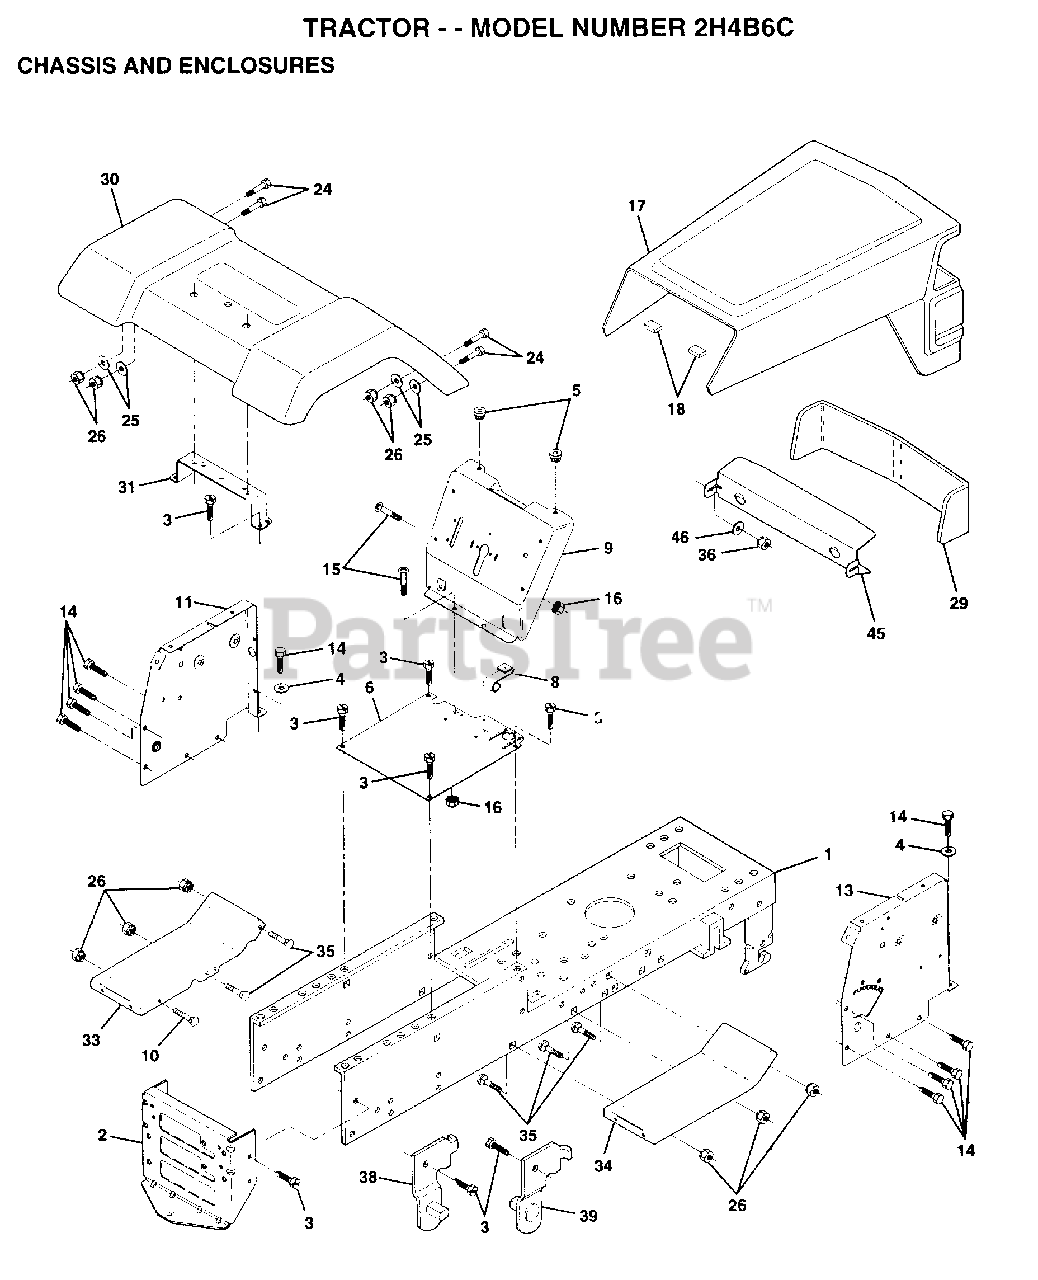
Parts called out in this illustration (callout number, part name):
1	CHASSIS.WLD.11GA
3	WASHER
8	"CLIP,INSULATOR"
9	DASH.SLKSC.LT.1PC
11	PANEL.DASH.LH.
14	SCREW LT
15	SCREW
17	HOOD/GRILL ASM
24	BOLT
25	WASHER
26	NUT
31	BRKT FENDER
33	FOOTREST LH
34	FOOTREST RH
35	BOLT
36	PAL NUT LT
38	BRACKET ASM LH
39	BRACKET ASM RH
46	RETAINER
